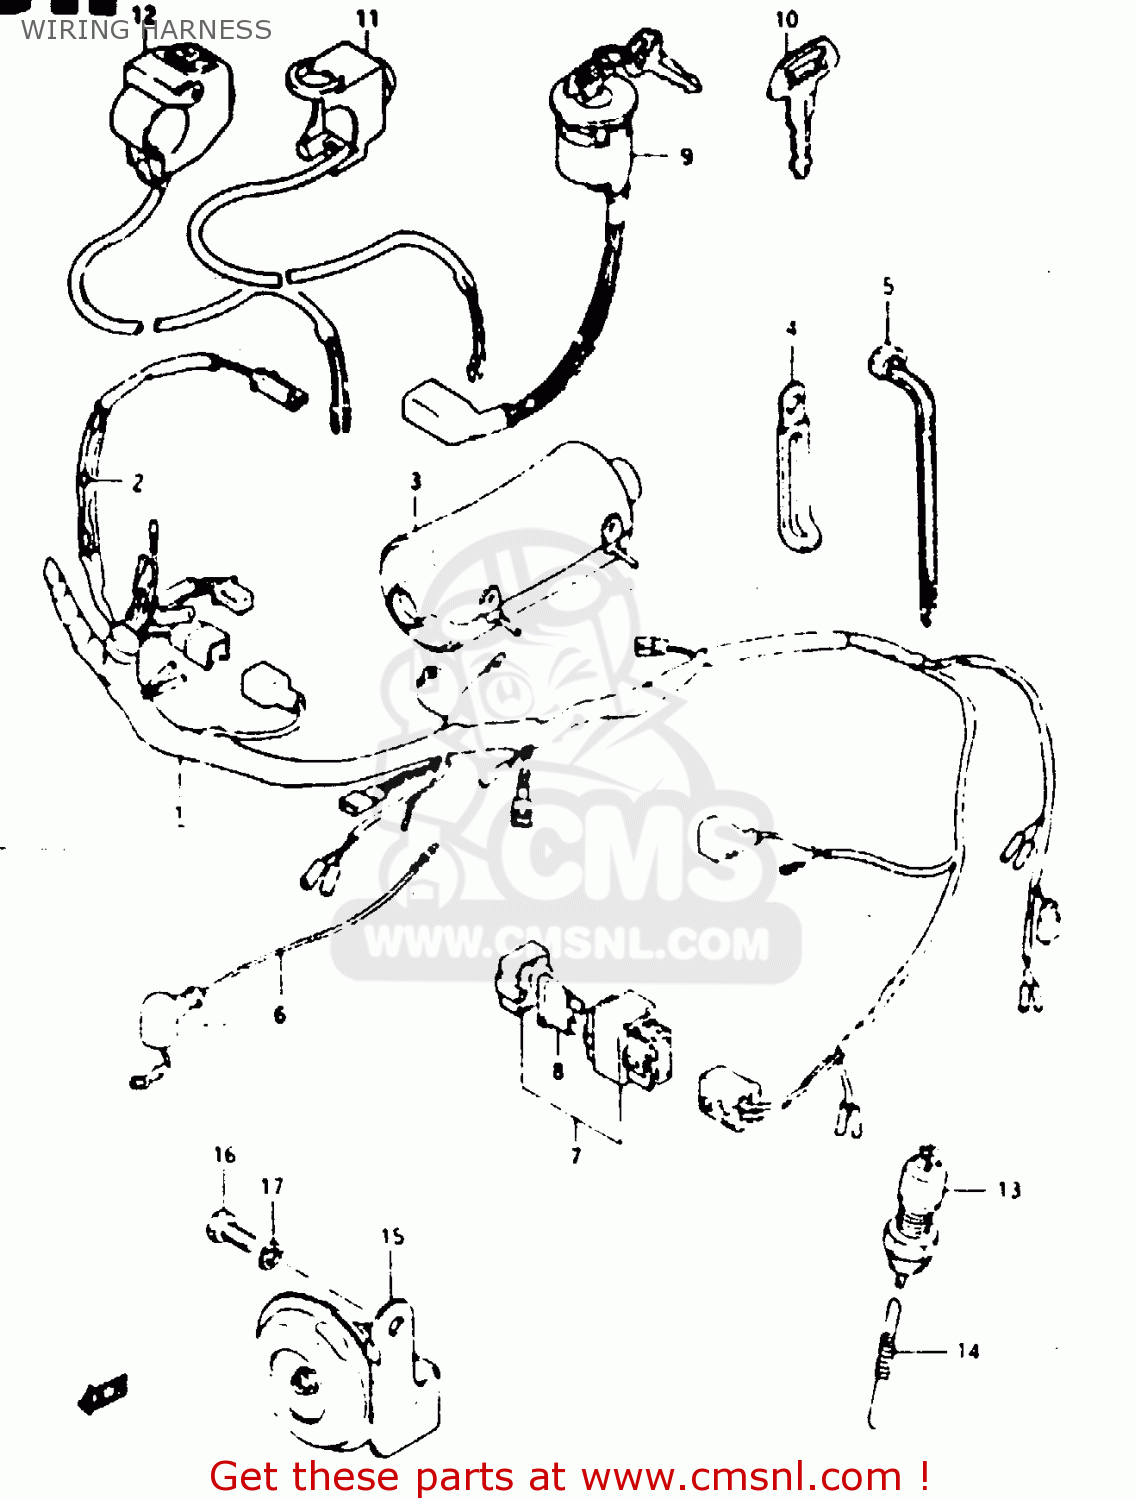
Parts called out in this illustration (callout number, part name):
1	WIRING HARNESS
2	DIODE
3	BOOT,WIRING HARNESS
4	CLAMP
5	CLAMP(L:125)
6	WIRE,WATER TEMPERATURE GAUGE
7	BOX ASSEMBLY,FUSE
8	FUSE(15A)
9	SWITCH ASSEMBLY,IGNITION
10	KEY,BLANK
11	SWITCH ASSY, ENGINE STOP
12	SWITCH ASSY,ENGINE STOP
13	SWITCH ASSEMBLY,STOP LAMP
14	SPRING
15	HORN ASSY
16	SCREW
17	WASHER,LOCK
